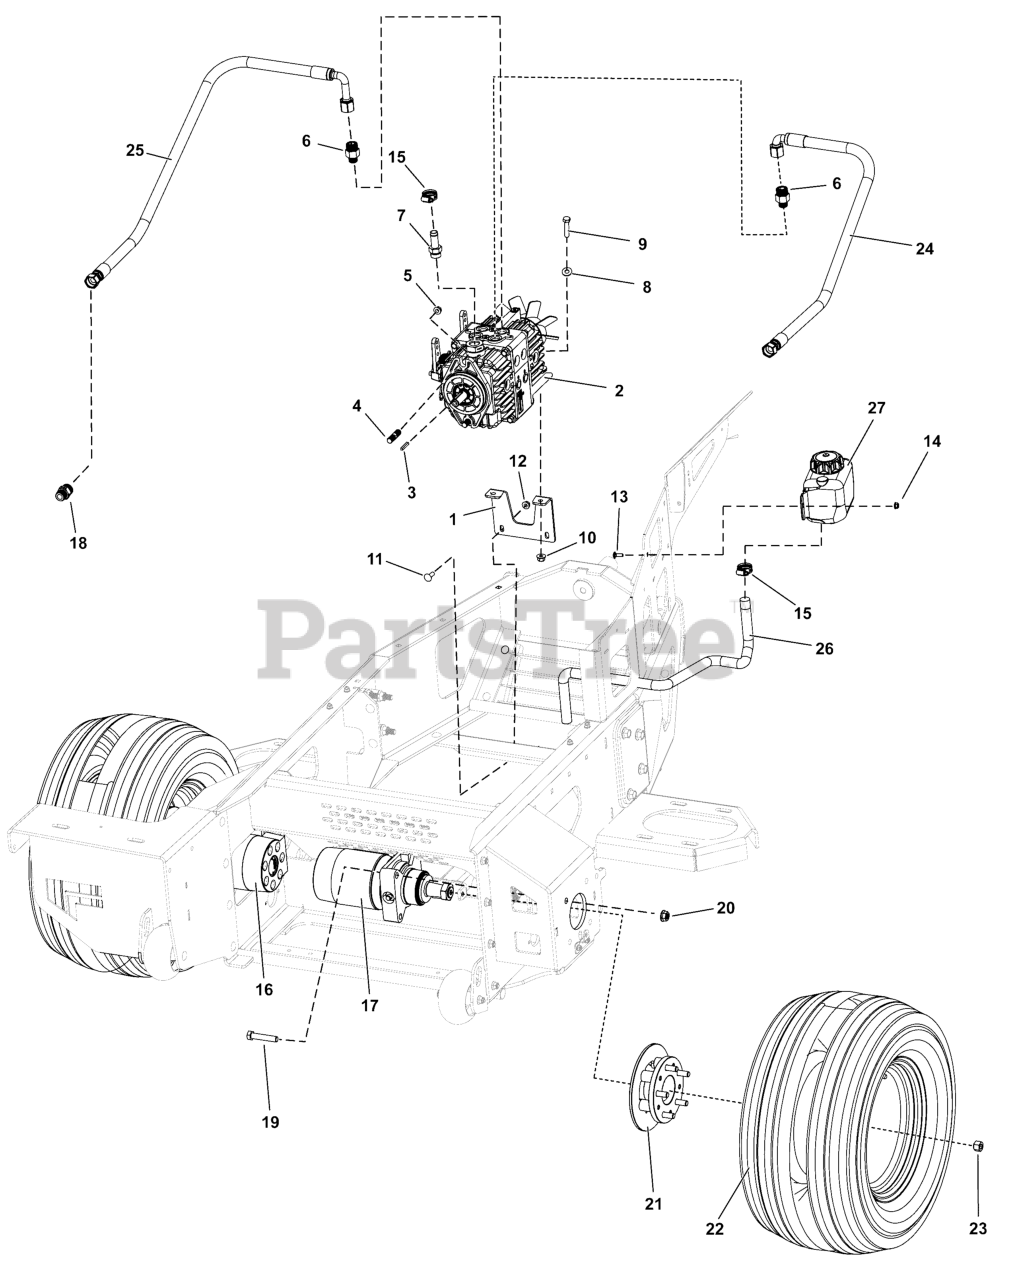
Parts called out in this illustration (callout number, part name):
1	BRACKET, PARKER HP2 PUMP
2	PUMP, TANDEM PARKER HP2
3	KEY 3/16" SQ X 1 1/4"
4	STUD, SETUP .500"-13 X .750", 1.875" OAL
5	NUT-HEX-NYLK, FLG .500"-13 SS188
6	ADP-HYD, STR 8 MORB - 10 MORFS
7	FTG-HYD, STR 10 HB X 10 MORB
8	WSHR-SS, FLT .438"X 1.000"X.083" USS
9	SCR-CAP, HEX .375"-16 X 1.7500" SS188
10	NUT-HEX-NYLK, FLG .375"-16 SS188
11	BLT-RDHDSQNK, .3125"-18 X 1.000" SS188
12	NUT-HEX-NYLK, FLG .3125"-18 SS188
13	BLT-RDHDSQNK .250"-20 X .750" SS188
14	NUT-HEX-NYLK, FLG .250"-20 SS188
15	CLAMP, HOSE, WORM GEAR, 11/16" TO 1-1/4"
16	TG0475UB081AAAC LH WHEEL MOTOR
17	TG0475UB080AAVH RH WHEEL MOTOR
18	ADP-HYD, STR 10 MORB - 10 MORFS
19	SCR-CAP, HEX .500'-13 X 2.500" G8 YZ
20	NUT, Hex Flange, Nylock, 1/2-13
21	ASM, WHEEL HUB
22	WHEEL/TIRE 24X12-12 GRASSMASTER
23	NUT-LUG, .500"-20 ZP
24	HOSE, HYDRAULIC ASSY 33.5 SHORT 90
25	HOSE, HYDRAULIC ASSY 35.0 LONG 90
26	HOSE, HYD EXPANSION .625" X 26.5"
27	TANK, EXP. 1 QUART W/ 5/8" STR FITTING
